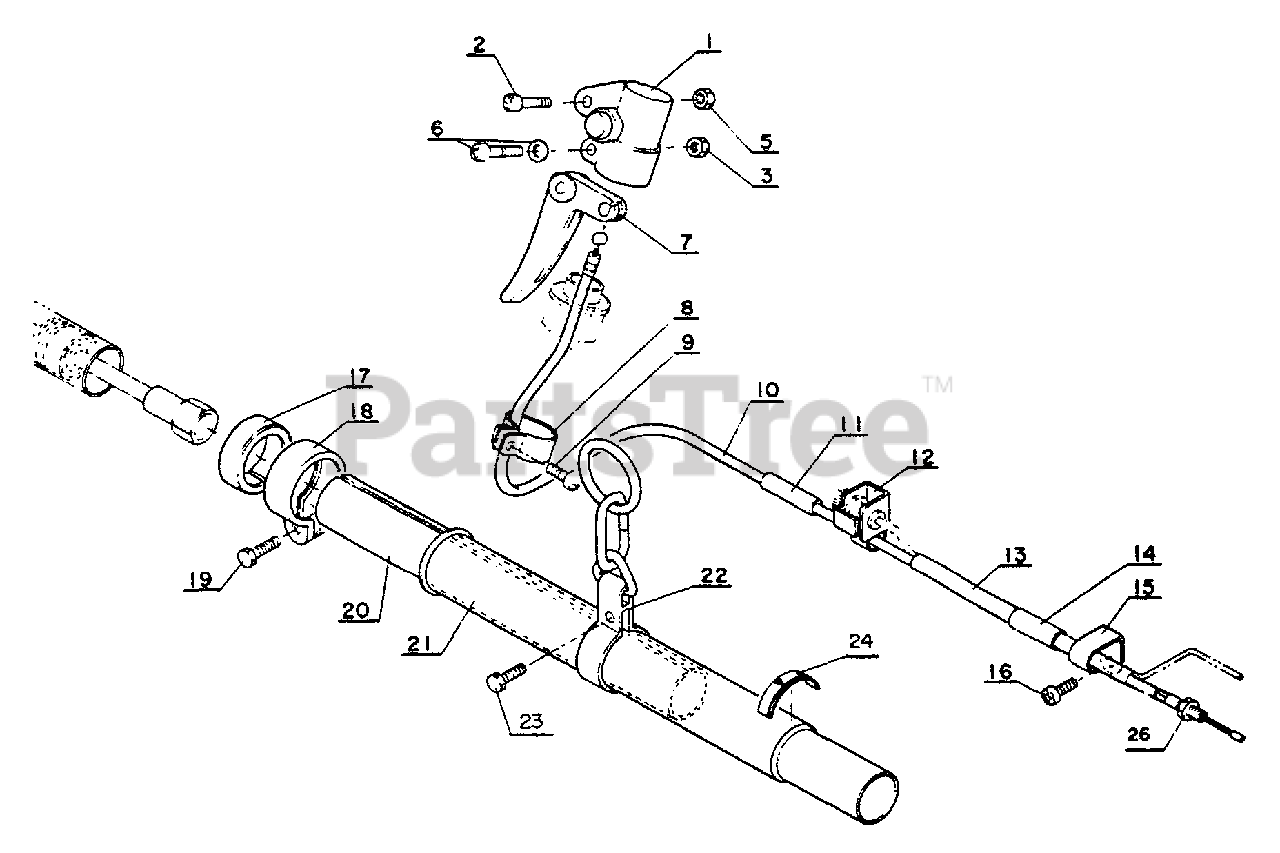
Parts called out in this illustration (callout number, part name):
1	CLAMP, THROTTLE CONTROL
3	NUT M5
5	LOCKNUT - 5
6	SCREW 5×28
7	TRIGGER, THROTTLE
9	SCREW 5×10
10	CABLE, THROTTLE
11	TUBE
12	CLIP
13	TUBE, VINYL
14	TUBE
15	CLAMP
16	SCREW 5×8
17	SPACER
18	CLAMP
19	BOLT - 5×16
20	BUSHING
21	TUBE, SWIVEL
23	BOLT 5×12
24	LABEL - ALIGNMENT
